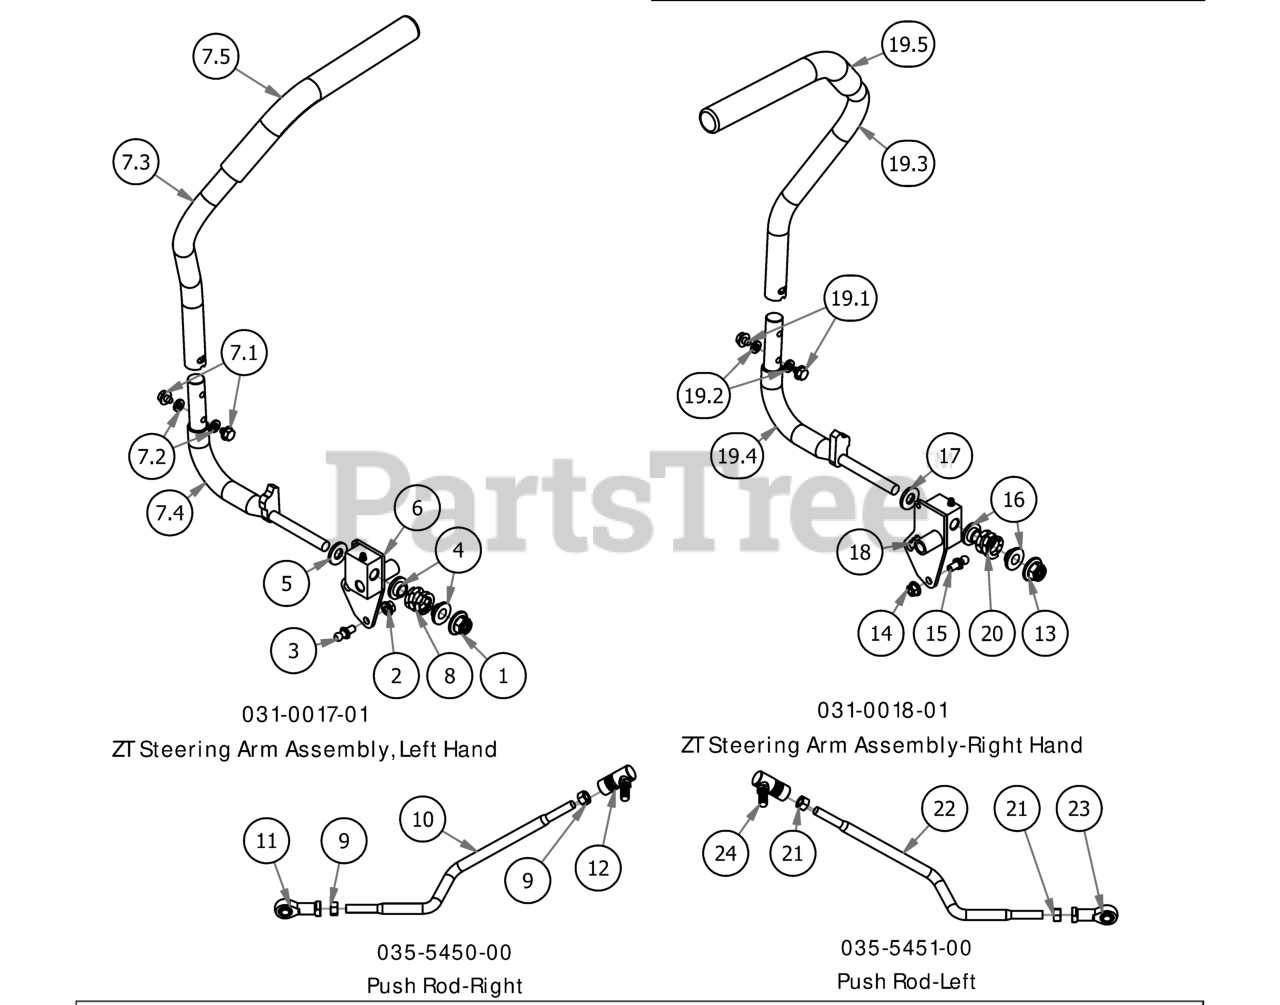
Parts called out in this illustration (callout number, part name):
1	1/2-13 Nylon Flange Nut
2	5/16" Flange Nut
3	10mm Damper Ball Stud-Steering
4	.515 ID Nylon Shoulder Washer
5	.505 Nylon Spacer
6	2017 Drive Lever Housing - Left
7	ZT Steering Arm-Left
7.1	5/16-18 1/2 HWH Bolt-Steering
7.2	5/16" Lock Washer
7.3	ZT Direction Steering Arm (Left)
7.4	Stering Arm Elbow (Left)
7.5	Rubber Grip
8	Drive Lever Spring
9	3/8" Fine Threaded Jam Nut
10	Push Rod - Right
11	Spherical Rod End - Outlaw
12	Quick Release Ball Joint
13	1/2-13 Nylon Flange Nut
14	5/16" Flange Nut
15	10mm Damper Ball Stud-Steering
16	.515 ID Nylon Shoulder Washer
17	.505 Nylon Spacer
18	2017 Drive Lever Housing - Right
19	ZT Steering Arm-Right
19.1	5/16-18 1/2 HWH Bolt-Steering
19.2	5/16" Lock Washer
19.3	ZT Direction Steering Arm (Right)
19.4	Stering Arm Elbow (Right)
19.5	Rubber Grip
20	Drive Lever Spring
21	3/8" Fine Threaded Jam Nut
22	Push Rod - Left
23	Spherical Rod End - Outlaw
24	Quick Release Ball Joint
